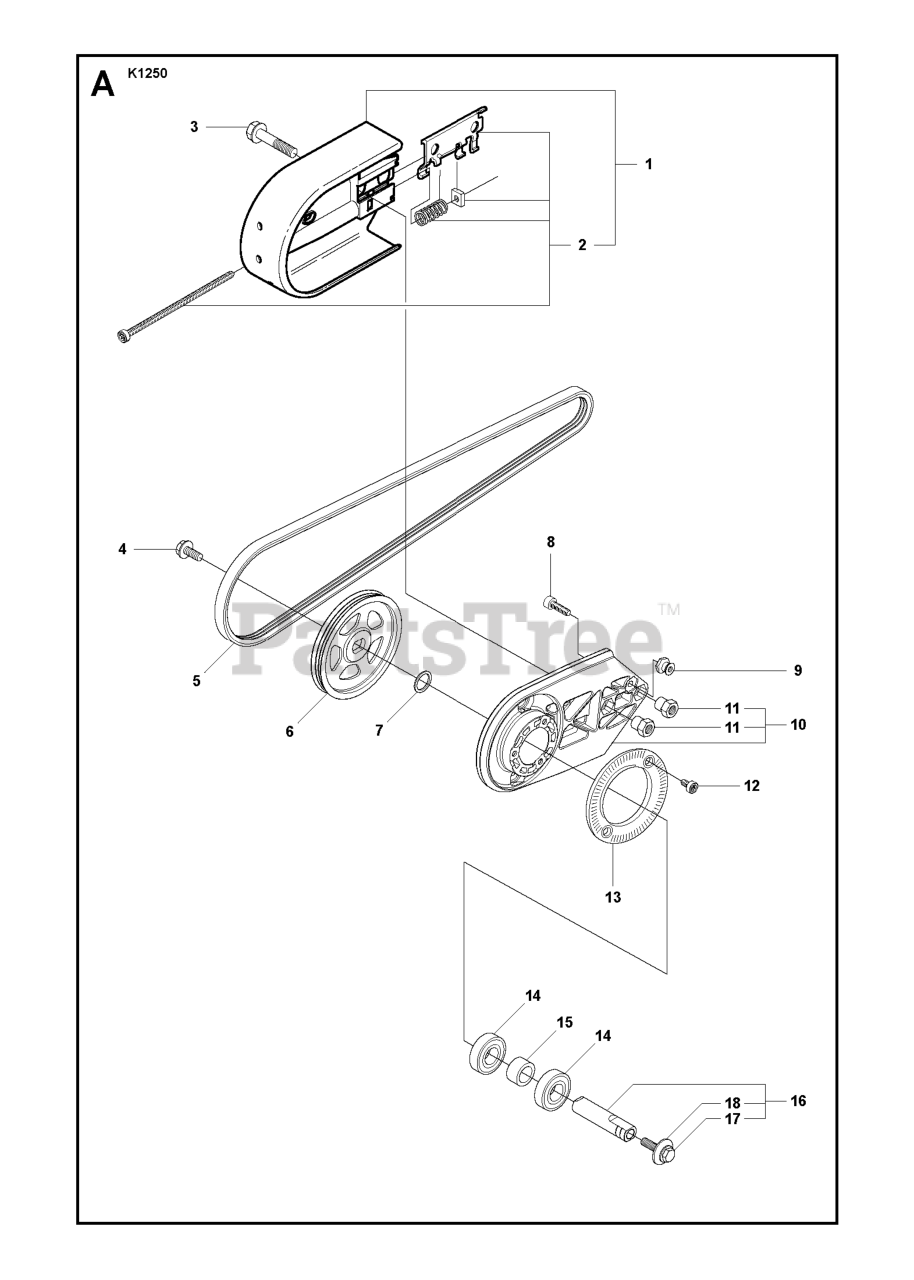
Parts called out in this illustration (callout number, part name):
1	COVER
5	BELT
6	RP PULLEY
7	WASHER 15X21
8	SCREW MC6S 5X16
10	HOUSING
14	BALL BEARING
17	SCREW
18	WASHER
